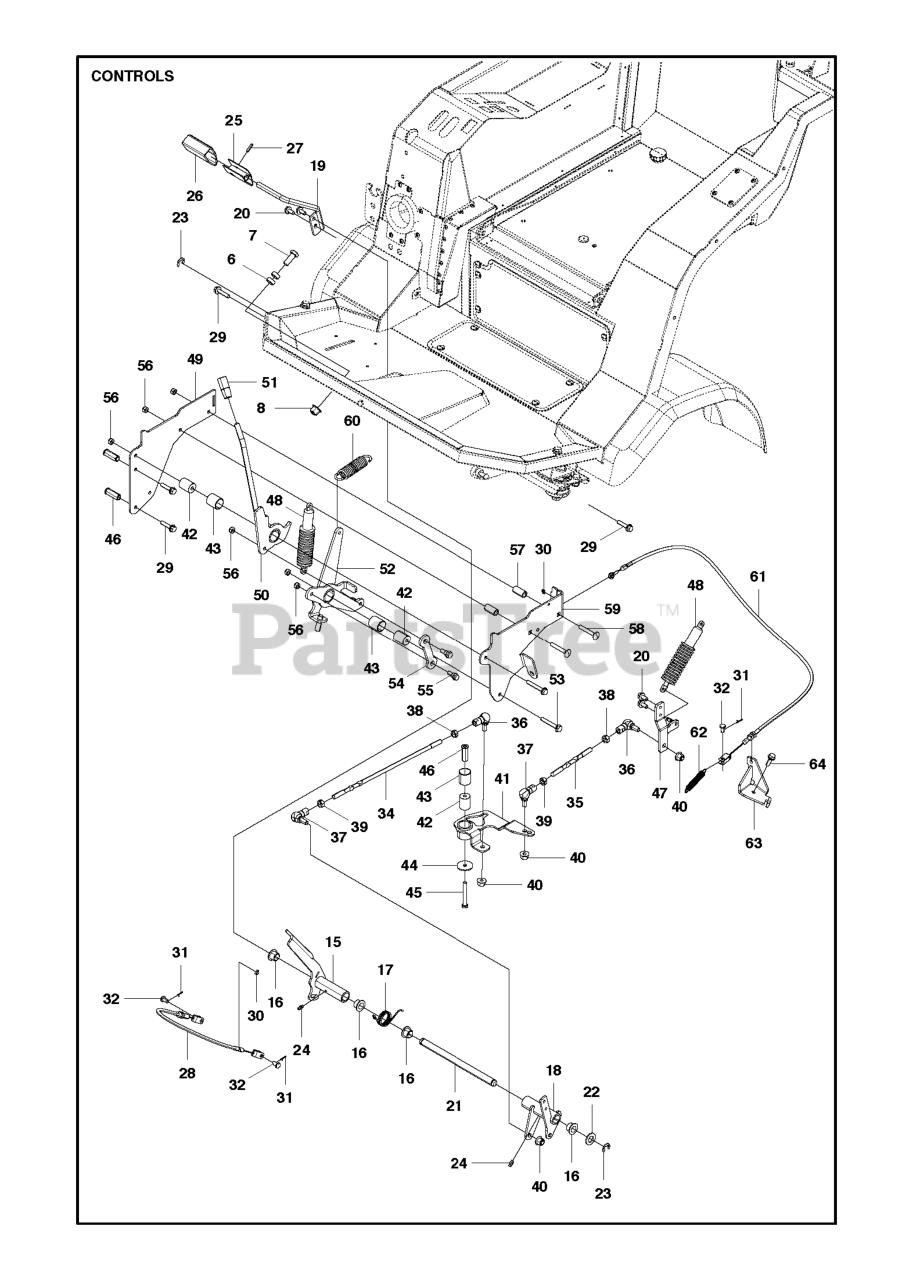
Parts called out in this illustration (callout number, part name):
16	BUSHING
24	GREASE NIPPLE
26	PEDAL RUBBER
29	SCREW EHHFM
31	Cotter Pin
32	Clevis Pin
43	BUSHING
48	SHOCK ABSORBER
53	SCREW EHHFM
56	LOCKNUT M8
64	BOLT
